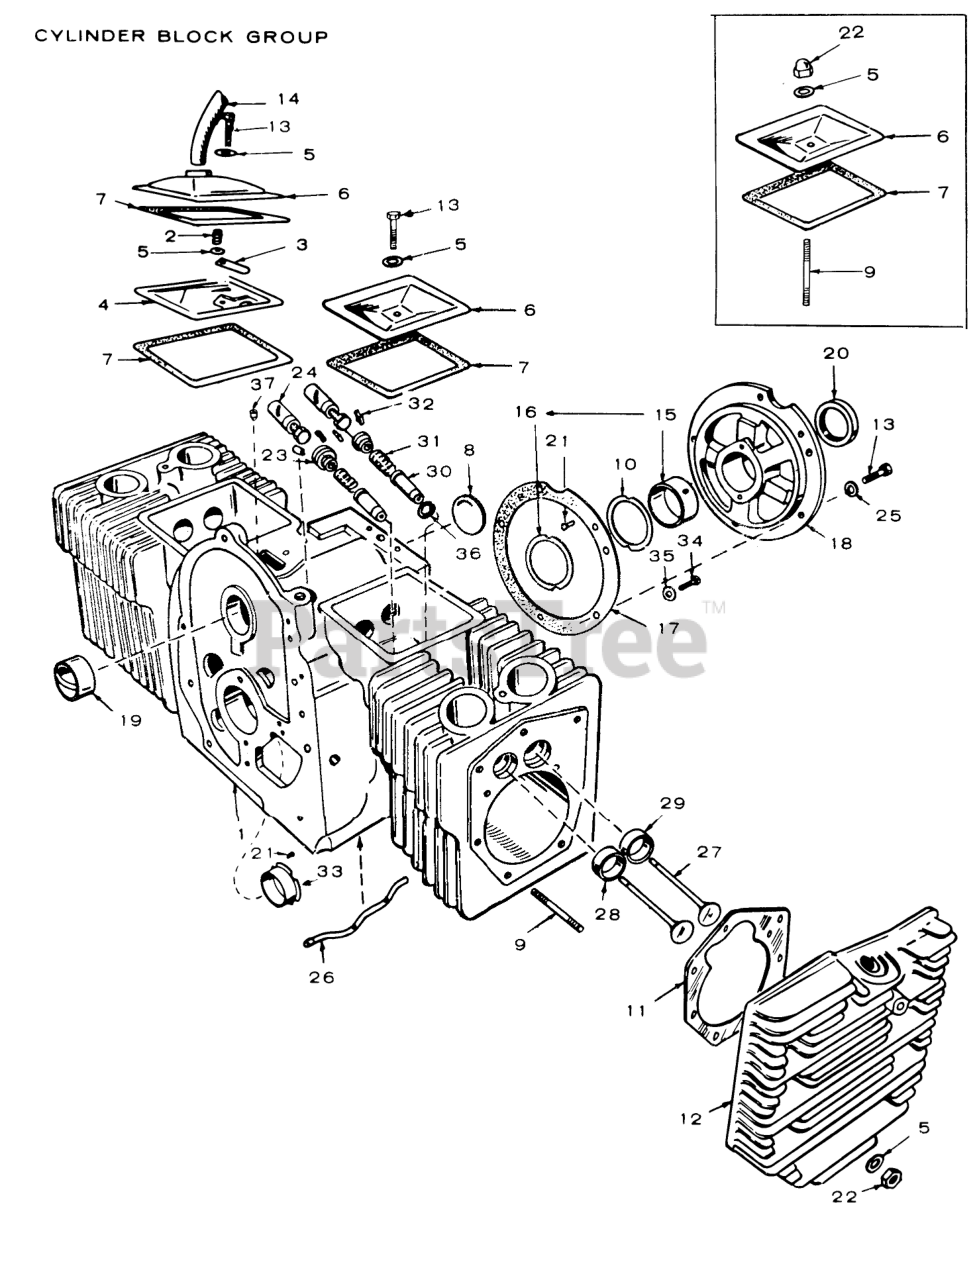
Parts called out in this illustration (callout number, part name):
1	Block Assembly, Cylinder, (Includes Parts Marked )
2	Spring, Breather Valve
3	Breather Valve
4	Breather Baffle
5	WASHER, FLAT
6	COVER, VALVE COMPARTMENT
7	Valve Cover Gasket
8	PlugCamshaft Expansion
9	Stud
10	Rear Bearing Shim
11	Gasket-Cylinder Head
12	HEAD, CYLINDER
13	SCREW, HEX CAP
14	TUBE-BREATHER
15	BEARING, CRANKSHAFT-REAR
16	Cranksft Bearing Thrust Washer
17	Gasket, Bearing Plate
18	Bearing Plate
19	Camshaft Bearing (Precision)
20	Bearing Plate Seal
21	Pin-Main Bearing Stop
22	Nut
23	Valve Spring Retainer
24	Tappet, Valve
25	Lockwasher-Rear Bearing Plate
26	Crankcase Oil Tube
27	Valve
28	Insert, Valve Seat-Exhaust
29	INSERT, VALVE SEAT-INTAKE
30	Valve Guide
31	Valve Spring
32	Lock-Valve and Spring Retainer
33	BEARING, CRANKSHAFT-FRONT
34	Cap Screw-Cylinder Block
35	Copper Washer 3/8-Oil Pressure
36	Gasket-Intake Valve Guide
37	Breather Hole Plug
